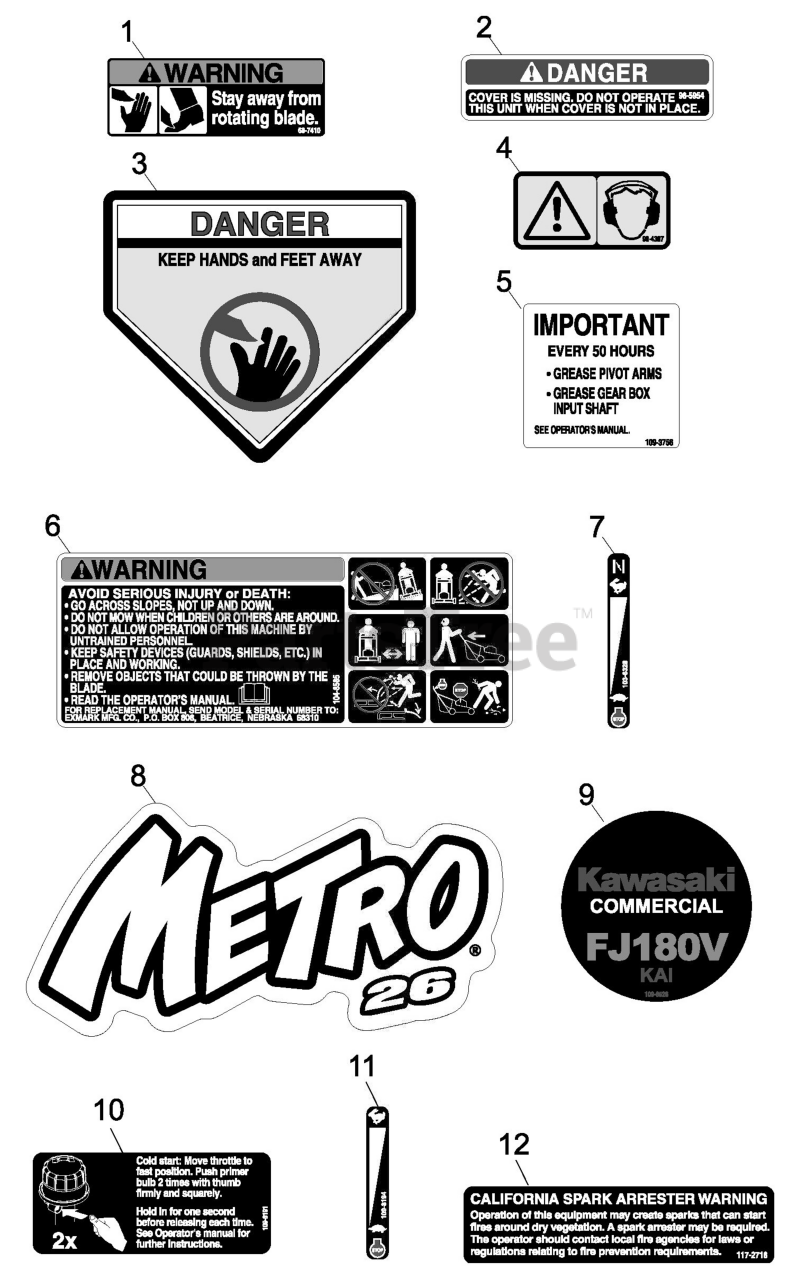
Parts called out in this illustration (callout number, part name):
1	DECAL-BLADE
2	DECAL-COVER, MISSING
3	DECAL-DANGER
4	DECAL-PROTECTION, EAR
5	DECAL,SERVICE M26
6	DECAL-WARNING
7	DECAL-THROTTLE / CHOKE
8	DECAL,METRO 26
10	DECAL, PRIMER
11	DECAL THROTTLE CONTROL BB
12	DECAL-ARRESTER, SPARK
